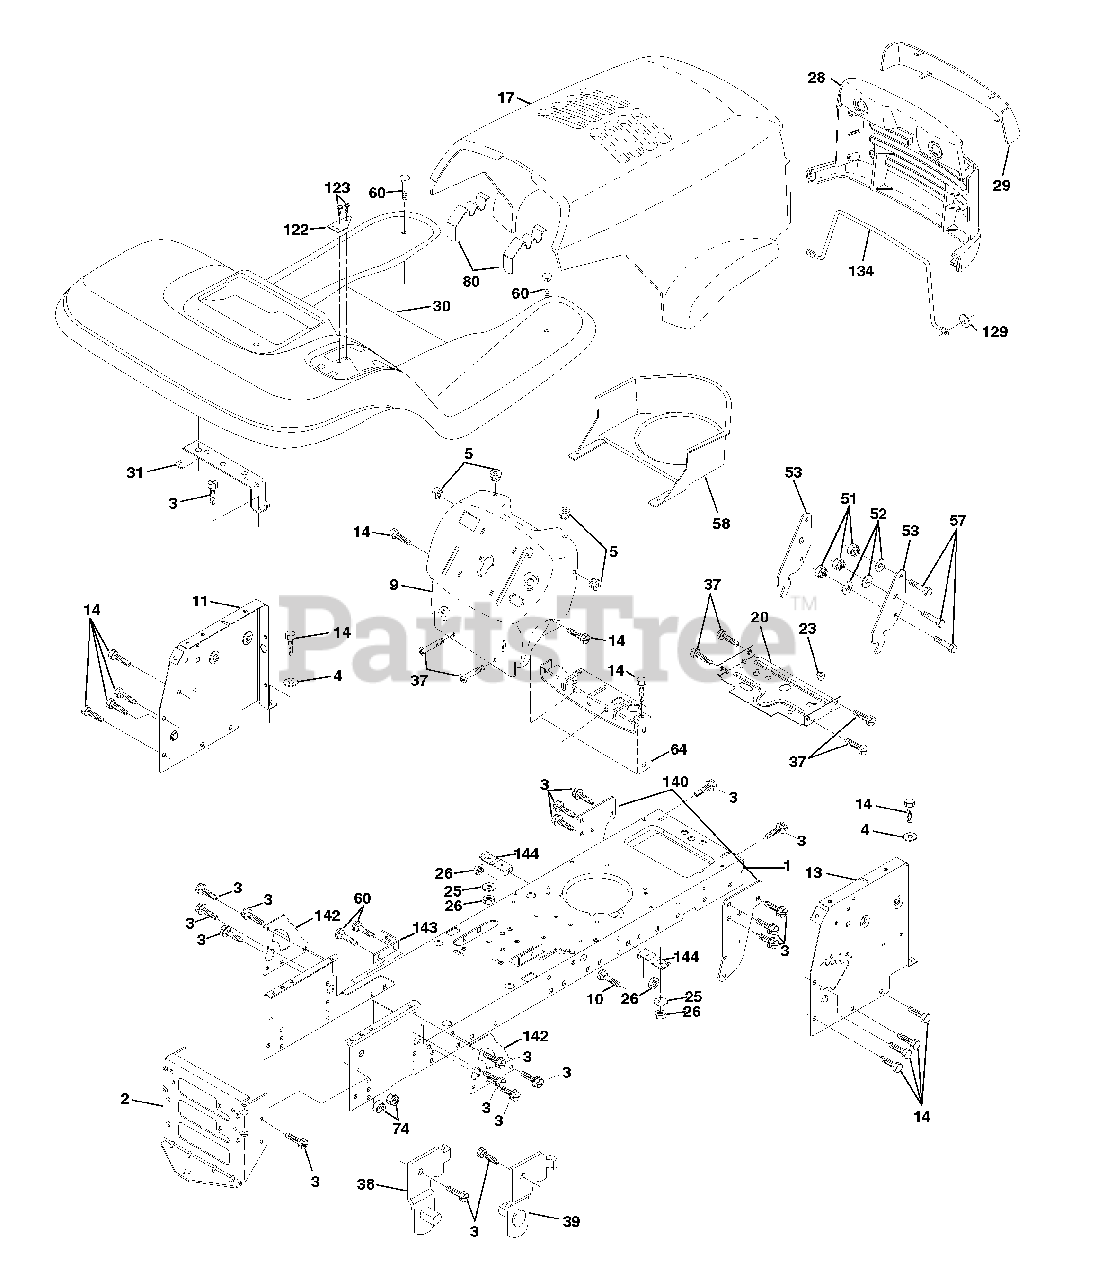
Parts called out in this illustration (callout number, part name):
1	Chassis Weldment
2	Drawbar, Stretch
3	Screw Thdrol 3/8-16x3/4 Ty-tt
4	Washer 13/32 x 3/4 x 16 Ga.
5	Bumper Hood/Dash
9	Dash P/L M, N/AMM N/HM Grey
10	Bolt Carriage 3/8-16 x 1
11	Panel Dash Lh
13	Panel Dash Rh
14	Screw Thdrol 3/8-16 x 1/2 Ty-tt
17	Hood LT/PL Husqvarna
20	Plate Mtg Battery Fuel Tank Fr
25	Washer 13/32 X 13/16 X 12 Ga
26	Nut Lock Hex W/Ins 3/8-16 Unc
28	Grille LT/PL Husqvarna
29	Lens LT/PL Husqvarna
30	Fender Footrest STLT Pnt
31	Bracket Support Fender
37	Screw Thdrol 6/16-18 x 1/2 TYT
38	Bracket, Asm. Pivot, L.H., Mower Rear
39	Bracket, Asm. Pivot, R.H., Mower Rear
51	Nut Lock Hex W/Ins 1/4-20
52	Washer 9/32 x 7/8 x 16 Ga.
53	Bracket Pnt. Pick off LT/PL Husqvarna
57	Bolt Hex 1/4-20 x 3/4
58	Air Duct Engine P/L
60	Bolt Rdhd Sqnk 3/8-16unc x 3/4
64	Dash Lower STLT
74	Nut Crownlock 3/8-16 UNC
80	Latch Hood Plm Husqvarna
122	Bracket Shift STLT
129	Washer 9/32 x 5/8 x 16 Ga.
134	Rod Support Hood LT/PL Husq.
140	Bracket Suspension Front
142	Plate Reinforcement STLT
143	Bracket Swaybar Chassis
144	Bracket Pnt Footrest STLT
